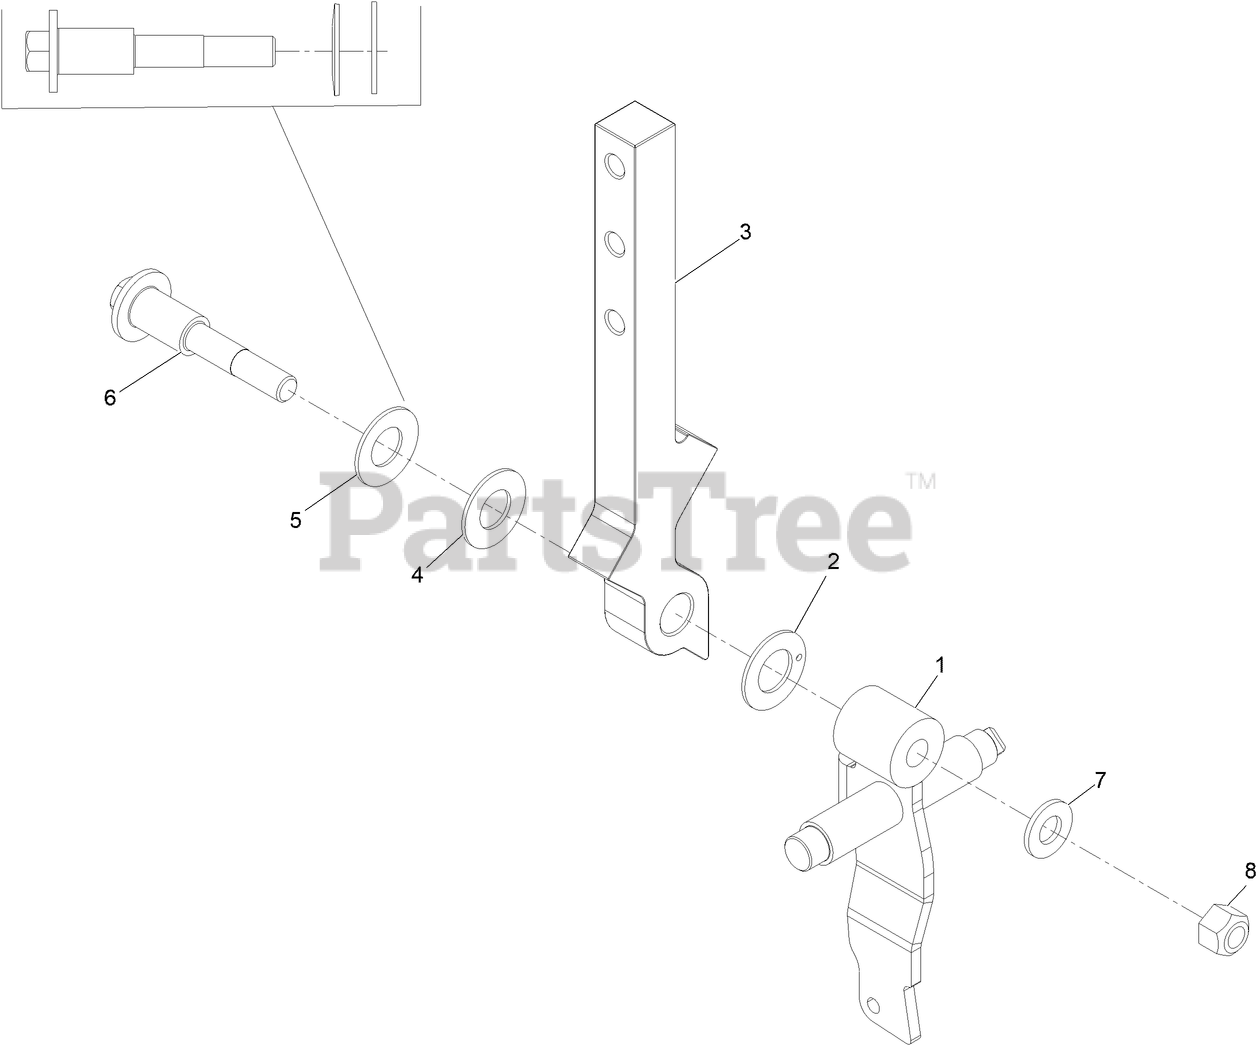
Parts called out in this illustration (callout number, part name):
1	Weld-Ctrl Arm RH
2	WASHER-FRICTION
3	ARM-CONTROL
5	WASHER-BELLEVILLE
6	BOLT-PIVOT
7	WASHER-FLAT
8	NUT-LOCK, CONE
